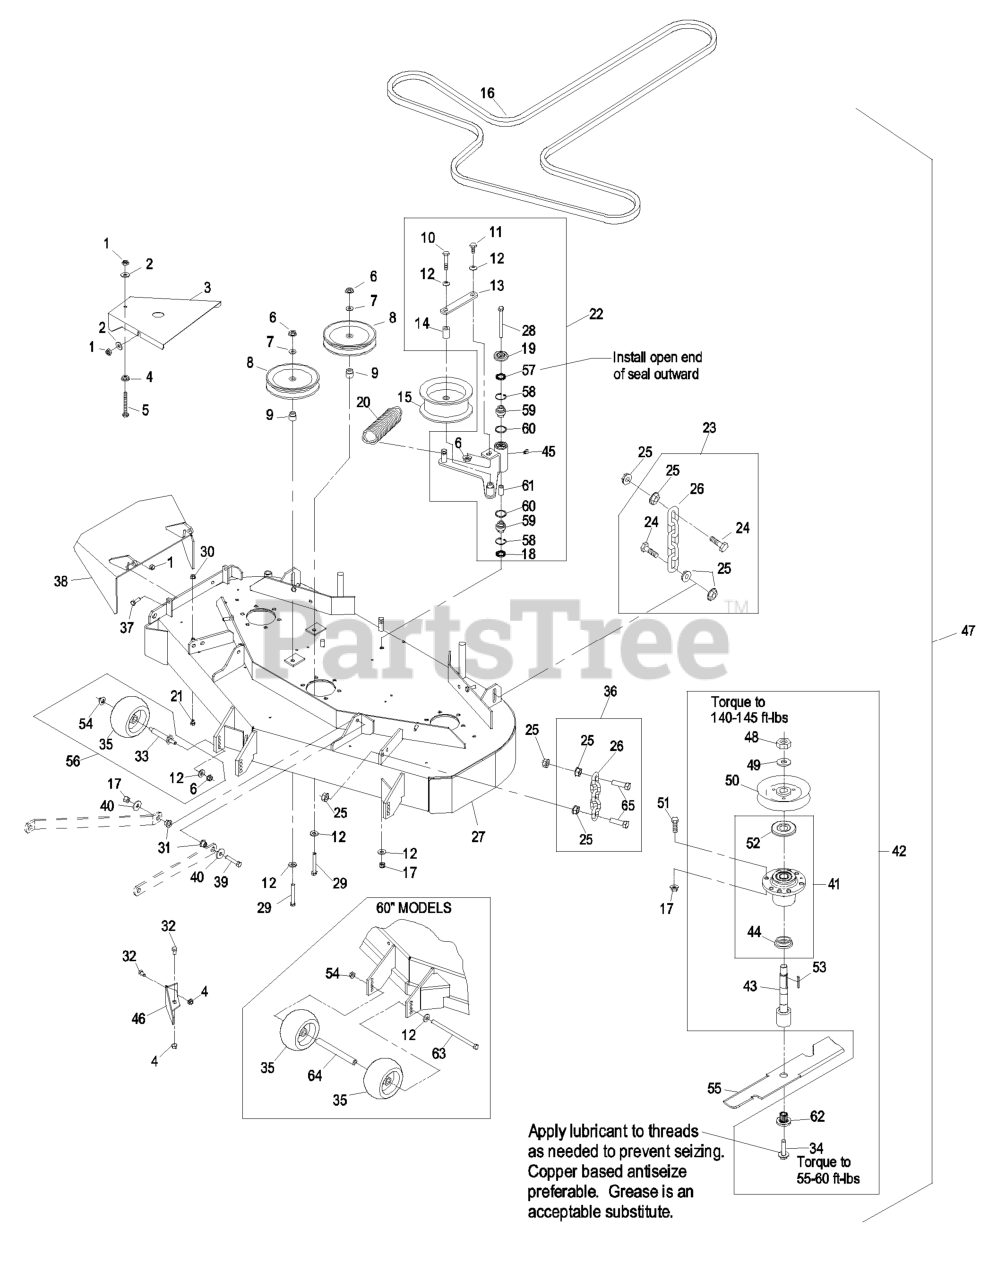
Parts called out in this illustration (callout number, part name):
1	NUT-LOCK, NI
2	WASHER-FLAT
3	BELT SHIELD W/ DECAL
5	BOLT,TAP HH
6	NUT-HHF, WHIZ
7	WASHER-FLAT
8	PULLEY-IDLER
9	BUSHING-IDLER
10	SCREW-HH
11	SCREW-HH
12	WASHER-BELLEVILLE
13	PLATE,GUIDE BELT (PLTD)
16	BELT,DECK DRIVE
17	NUT-LOCK, NI
18	SEAL-LIP, DOUBLE
19	GUARD-TOP
21	SCREW-HH
22	KIT,DECK IDLER LHP/LCT
23	DECK CHAIN ASM
24	SCREW-CAP, HH
26	CHAIN-LIFT, DECK
27	ASM,DECK W/DECALS LCT48
28	SCREW-HH
29	SCREW-HH
31	SPACER-STRUT
32	SCREW-HH
35	ROLLER-SCALP, ANTI
36	DECK CHAIN ASM
37	SCREW-HH
38	WLD,CHUTE 48
39	SCREW-HH
41	KIT, CUTTER HOUSING
42	ASM, CUTTER HSG
43	KIT, SPLINED SPINDLE 103-
44	SPACER-GUARD, BOTTOM
45	FITTING-GREASE, 90 DEG
47	Asm, Deck Complete
50	SHEAVE,W/HUB 5.72
51	SCREW-HH
52	GUARD-BEARING, TOP
53	KEY-RECTANGLE
54	Nut-Nyloc 3/8-16 Flg
57	SEAL-LIP, SINGLE
58	RING-SNAP
59	BEARING-SPHERICAL
62	BUSHING,SPLINED
63	SCREW-HH
64	SPACER-WHEEL
65	SCREW-HH
